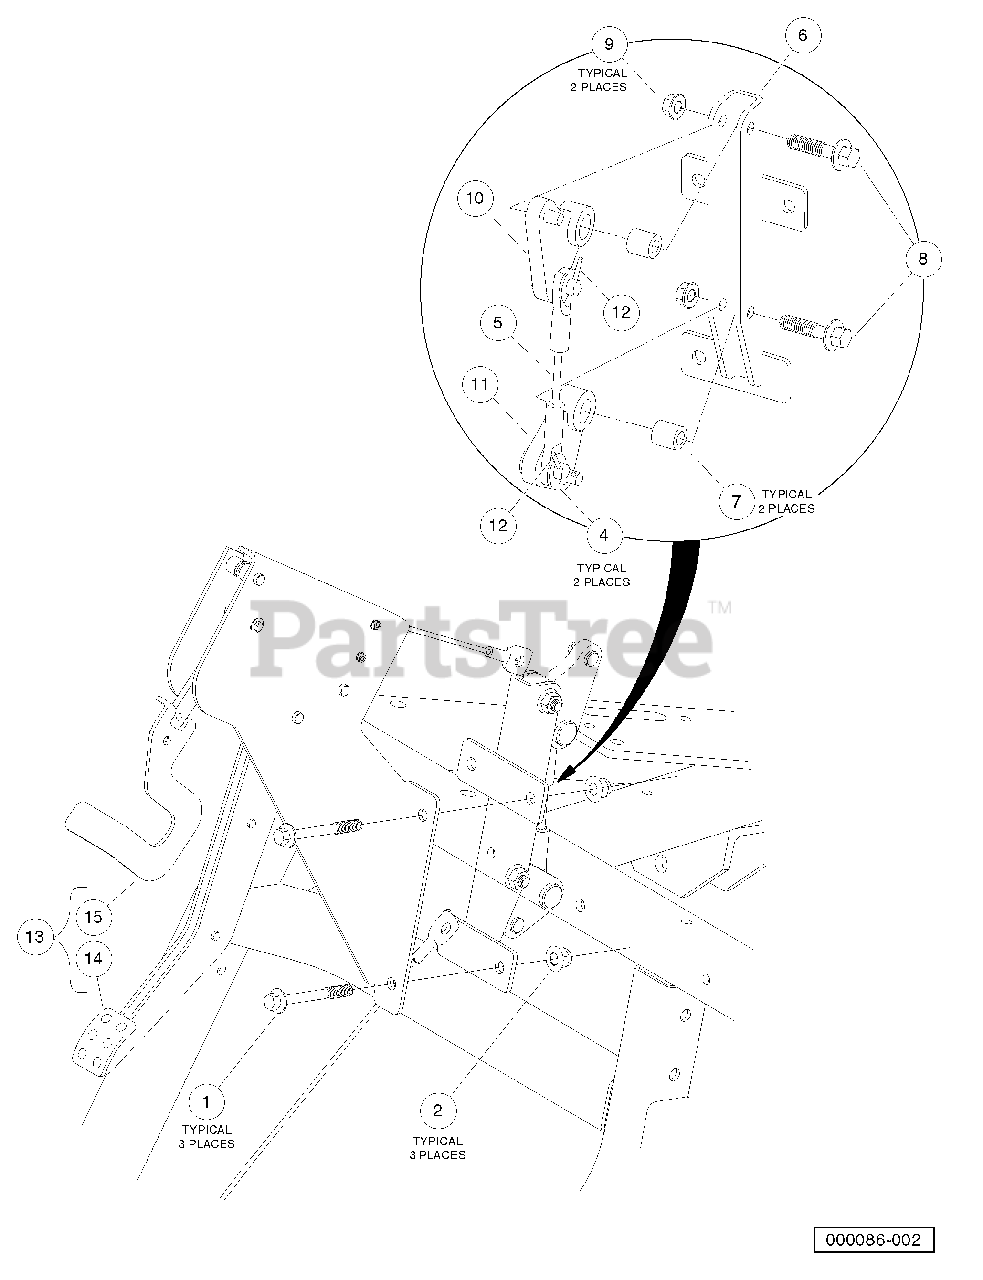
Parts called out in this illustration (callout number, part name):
1	Bolt Flanged Head, M8 X 1.25 X 65
2	Lock Nut, Flg M8 X 1.25 Nylon
3	Asm, Sub, Bracket, Park Brake
4	Washer, Flat, 3/8, Blk Fin
5	Cable, Crank, Bell
6	Brkt, Bellcrank, Park Brake
7	Spacer Pivot, Park Brake
8	Bolt Flg, M8x1.25 X 35, Gr10.9
9	Nut Flg M8 X 1.25 Gr 10
10	Asm, Bellcrank, Upper
11	Asm, Bellcrank, Lower
12	Pin, 3/32 X 1.00 Sq Cut Cotter
13	Asm, Pedal, Brake, Hard
14	Pedal, Brake, Park
15	Handle, Release, Park Brake
